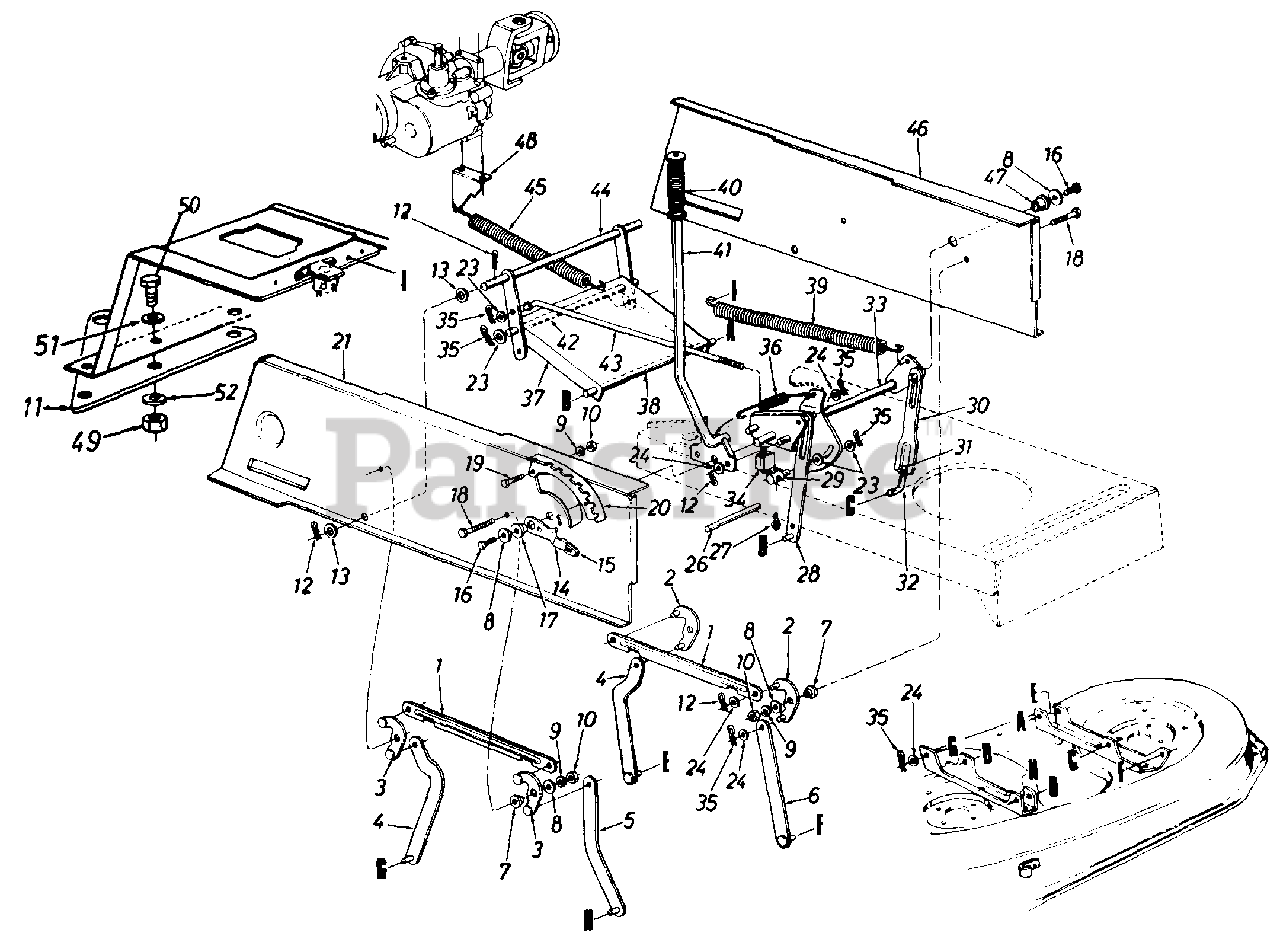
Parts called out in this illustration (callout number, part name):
1	Connecting Rod
2	Pivot Link Ass'y. - L.H.
3	Pivot Link Ass'y. - R.H.
7	Shld. Spacer .318" I.D.
8	Fl-Wash. .344" I.D. x .62"
9	L-Wash. 5/16" I.D.
10	Hex Nut 5/16-18 Thd.
11	Hitch Plate Extension
12	Cotter Pin 1/8" Dia.
13	Fl-Wash. .635" I.D. x 1.0" O.D.
14	Deck Lift - Down Stop
16	Hex Wash. TT-Tap Scr. 5/16-18 x .75" Lg.
17	Flange Brg. .63" I.D.
18	Hex Wash. Wd. Scr. 5/16-18 x .875" Lg.
19	Hex Bolt 5/16-18 x .75" Lg.
20	Index Brkt.
21	Upper Frame - R.H.
23	Fl-Wash. .385" I.D. x .87" O.D.
24	Fl-Wash. .531" I.D. x .93" O.D.
26	Running Board Rod
27	Truss Mach. Scr. #10 x .5" Lg.
31	Hex Nut 1/2-20 Thd. (Gr. 5)
32	Lift Link Adjuster
33	Lift Shaft Ass'y.
34	Safety Switch (Deck)
35	Inter. Cotter Pin 3/8" Dia.
36	Extension Spring
37	Stabilizer Bracket
38	Shaft 1/2" Dia. x 10.28" Lg.
39	Extension Spring
40	Grip (Lift Handle)
41	Deck Lift Handle Ass'y.
42	Shaft 3/8" Dia. x 9.34" Lg.
43	Disengagement Rod
44	Stabilizer Shaft Ass'y.
45	Extension Spring 7.58" Lg.
46	Upper Frame - L.H.
47	Flange Brg. .632" I.D.
49	Hex Nut 7/16-14 Thd. (Gr. 5)
50	Hex Bolt 7/16-14 x 1" Lg.
51	Bell-Wash. .46" I.D. x 1.13" O.D.
52	Fl-Wash. .469" I.D. x .875" O.D.
